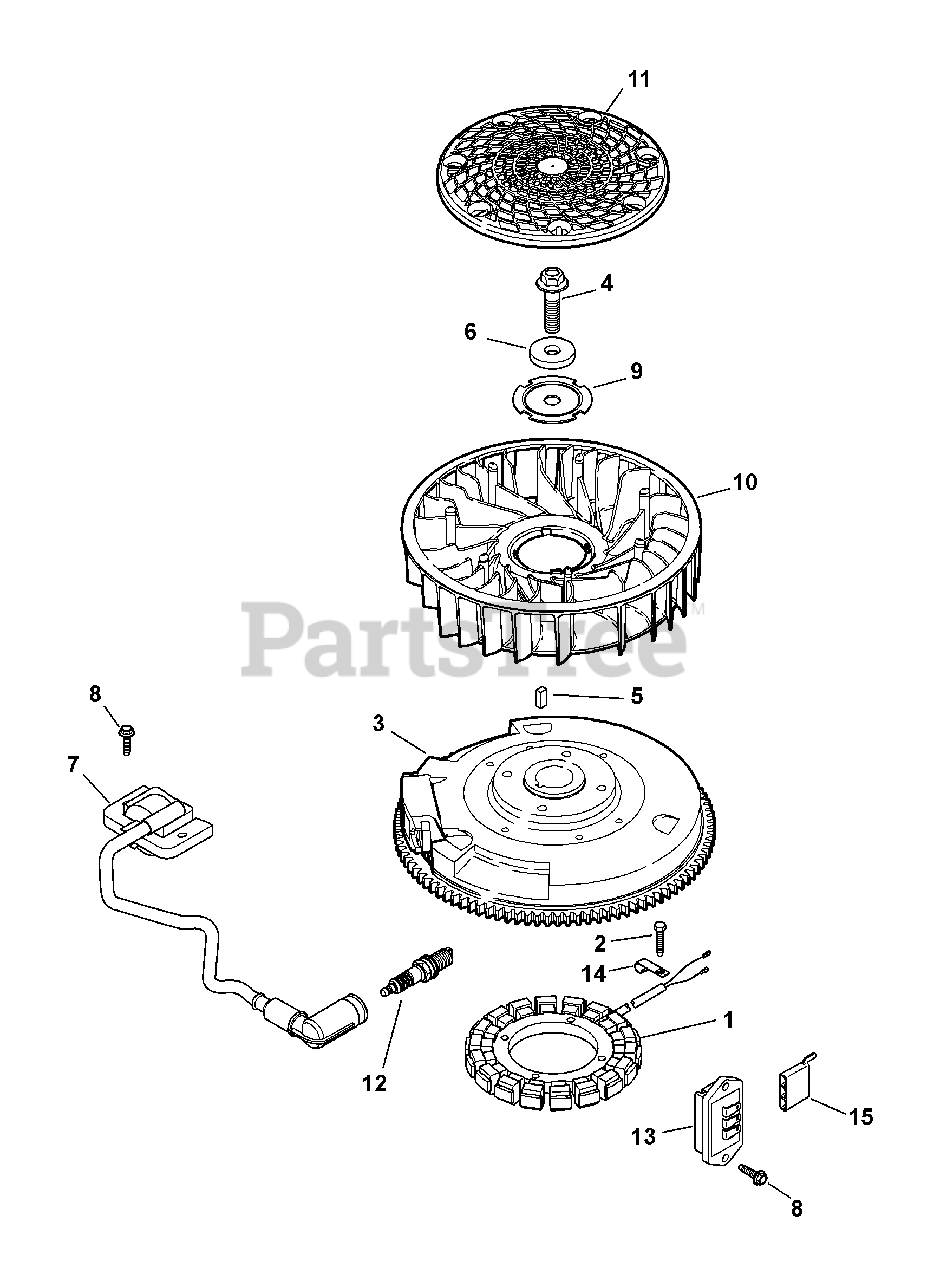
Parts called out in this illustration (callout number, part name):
1	15 Amp Stator Kit
2	Thd. Frm. Screw, M5 X 0.8 X 25
3	Flywheel
4	Screw, Hex Flange
7	Ignition Module
8	Flg. Thd. Frm. Screw, M5 X .8 X 20
9	Fan Mounting Plate
12	Spark Plug
13	Regulator/Rectifier
